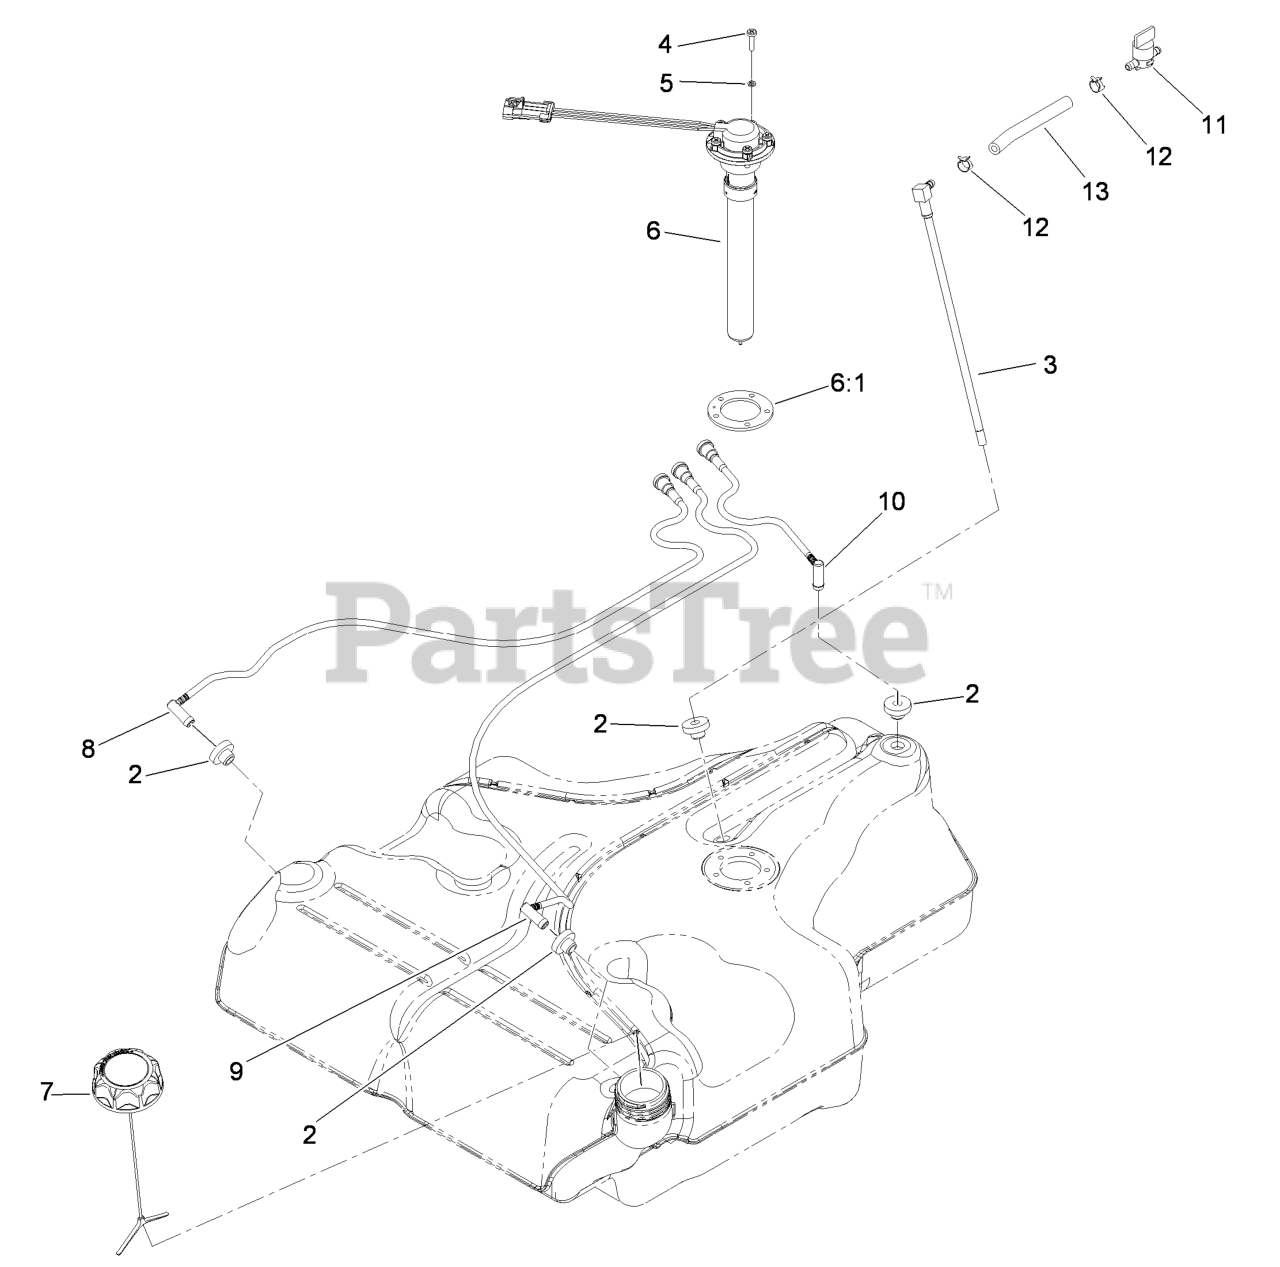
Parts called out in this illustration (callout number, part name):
2	BUSHING
3	FUEL LINE KIT (WITH GROMMET)
4	SCREW-PAN
5	WASHER-LOCK
6:1	GASKET-SENDER, FUEL
8	RH VENT LINE KIT (WITH GROMMET)
9	LH VENT LINE KIT (WITH GROMMET)
10	REAR VENT LINE KIT (WITH GROMMET)
11	VALVE-FUEL
12	CLAMP-HOSE
13	HOSE-FUEL
